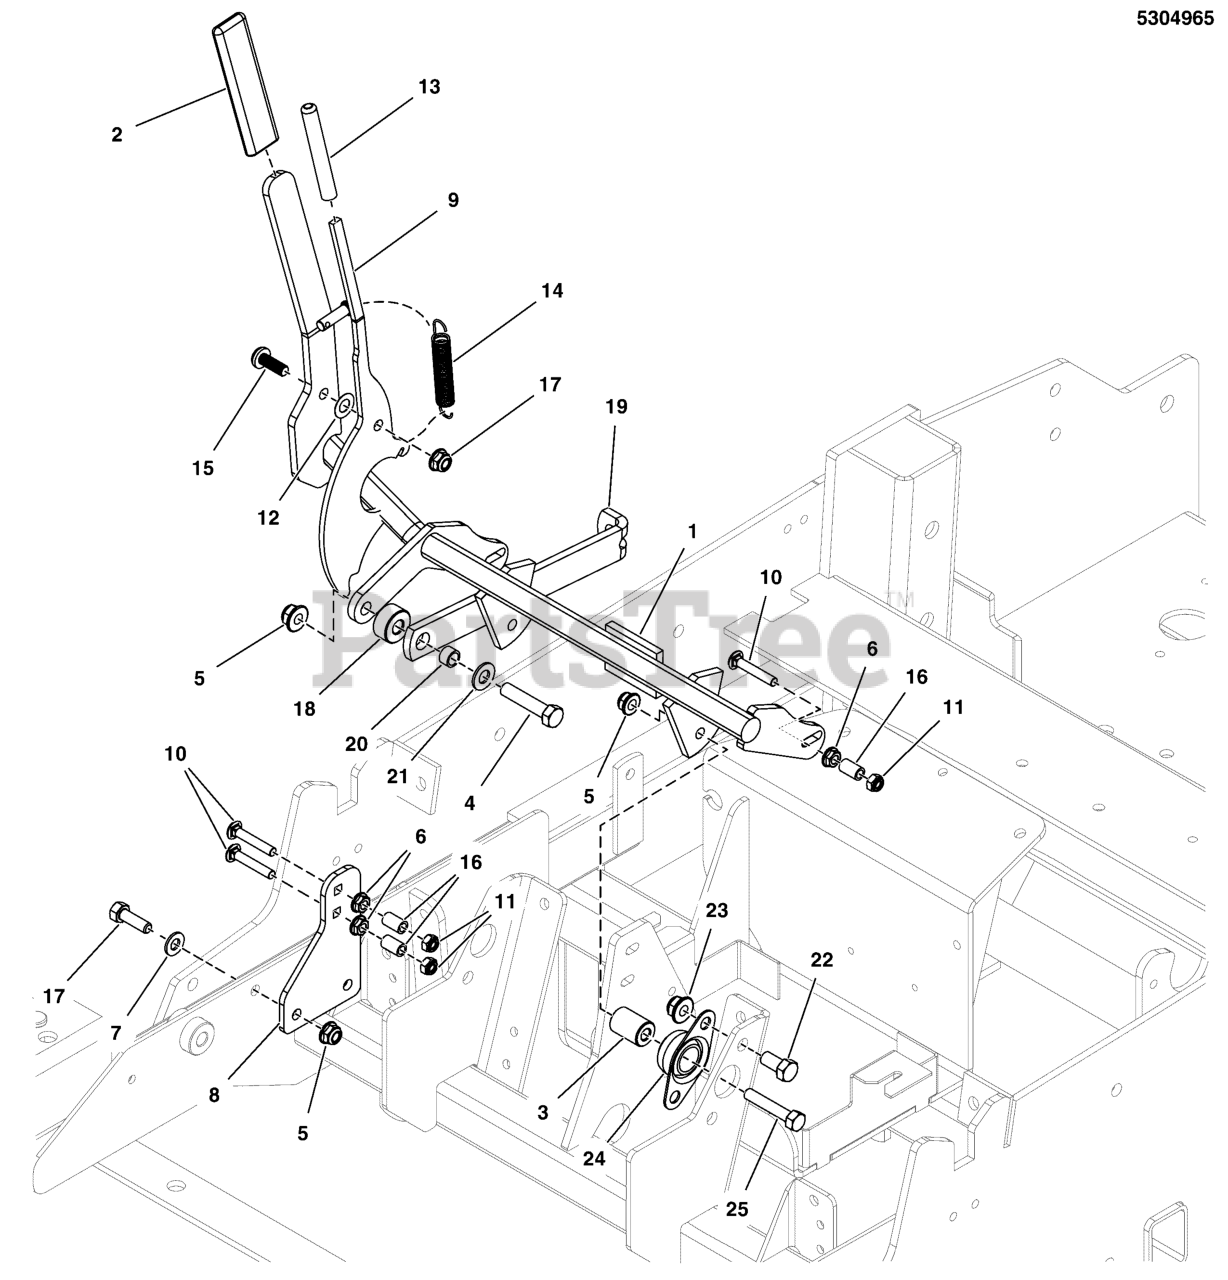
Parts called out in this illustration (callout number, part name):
1	WELD, BRAKE SHAFT, F160 CE - BLK
2	GRIP, FOAM, 1/4 X 1 X 4.1
3	SPACER, .32 X .75 X 1.06, PM
4	BOLT, 3/8-16 X 1-1/2" GD5 CZ
5	NUT, 5/16-18 HEX NYLOCK FLANGE NUT
6	NUT, 1/4-20 HEX SERR. FLANGE
7	WASHER, 5/16" SAE
8	PLATE, CE BRAKE LOCK TAB - BLK
9	LEVER, BRAKE, IS2600 EU - BLK
10	BOLT, 1/4-20 X 1.500, GR5, SQ, ZINC/CLEAR
11	NUT, 1/4-20 HEX NYLON LOCK
12	WASHER,WAVE,M10
13	COVER, VINYL HANDLE
14	SPRING-EXT, .500 OD X 3.50 LG X .058 WR
15	SCREW, TRUSS HD TORX DR5/16-18X0.875 BLK
16	SPACER, .52 X .38 X .63, CZ
17	BOLT, 5/16-18 X 1" GRD5 YZ
18	SPACER, .39 X 1.00 X .25, PM, CZ
19	LINK, BRAKE LOCK - BLK
20	SPACER, .38 X .50 X .31, CZ
21	WASHER, 3/8 SAE
22	BOLT, 3/8-16 X 3/4" GD5 CZ
23	NUT, 3/8 - 16 HEX NYLOCK FLANGE
24	BEARING, BRONZE FLANGE, 3/4"
25	BOLT, 5/16-18 X 1-3/4" GD5 YZ
